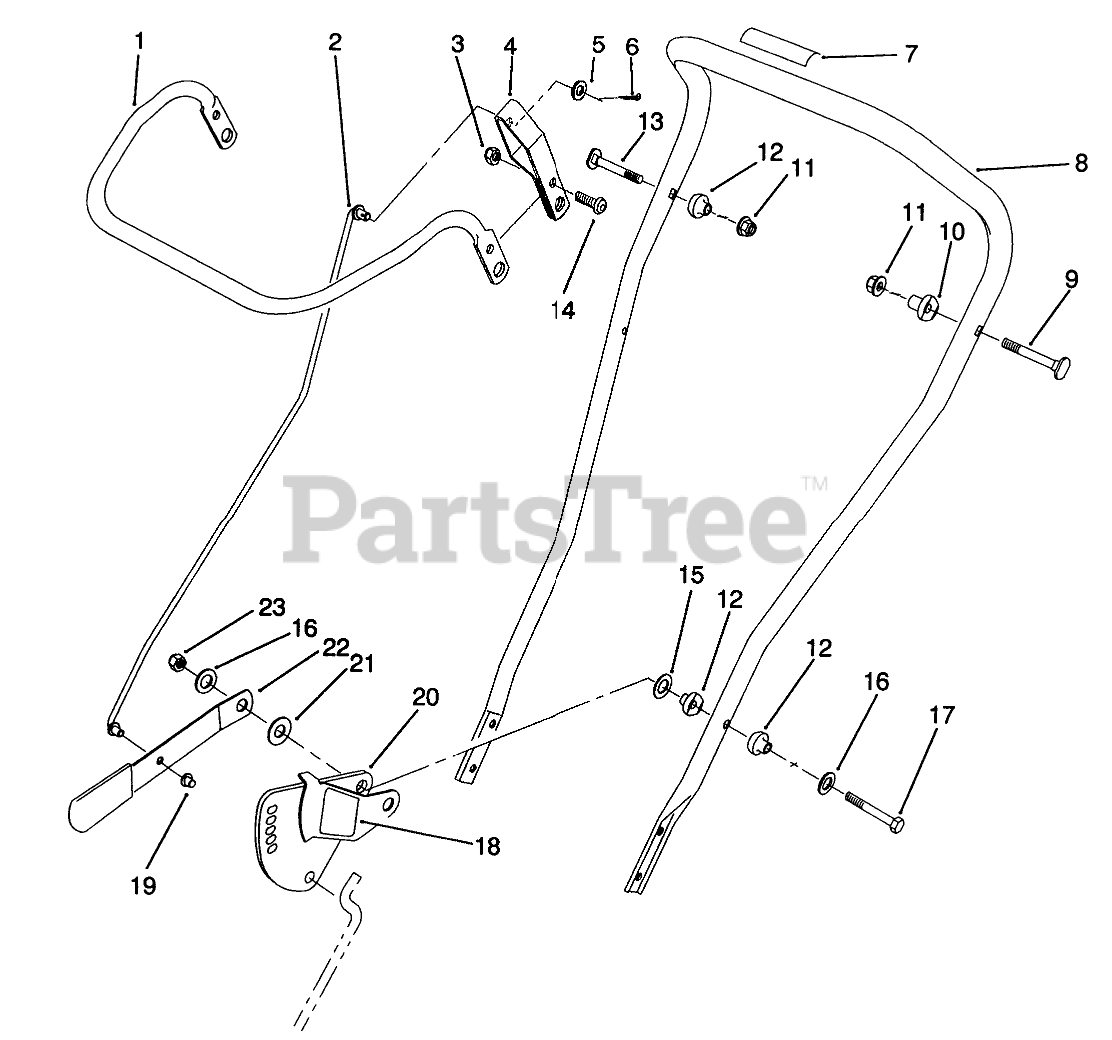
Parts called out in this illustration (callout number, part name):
1	Bar-Control
2	UPPER CONTROL ROD
3	NUT-LOCK, NI
4	CONTROL BAR BRKT.
5	WASHER-FLAT
6	PIN-COTTER
7	DECAL
8	UPPER HANDLE
9	5/16-18 X 2 HNDLE SCREW
10	SPACER-SUPPORT
11	NUT-LOCK, NI
12	PIVOT SPACER
13	SCREW-HANDLE
14	SCREW-HSBH
15	WASHER
16	WASHER-PLAIN
17	SCREW-HH
18	DECAL
19	PUSHNUT
20	ADJ.PLATE WA
21	WASHER
22	ADJ.HANDLE
23	NUT-LOCK, NI
